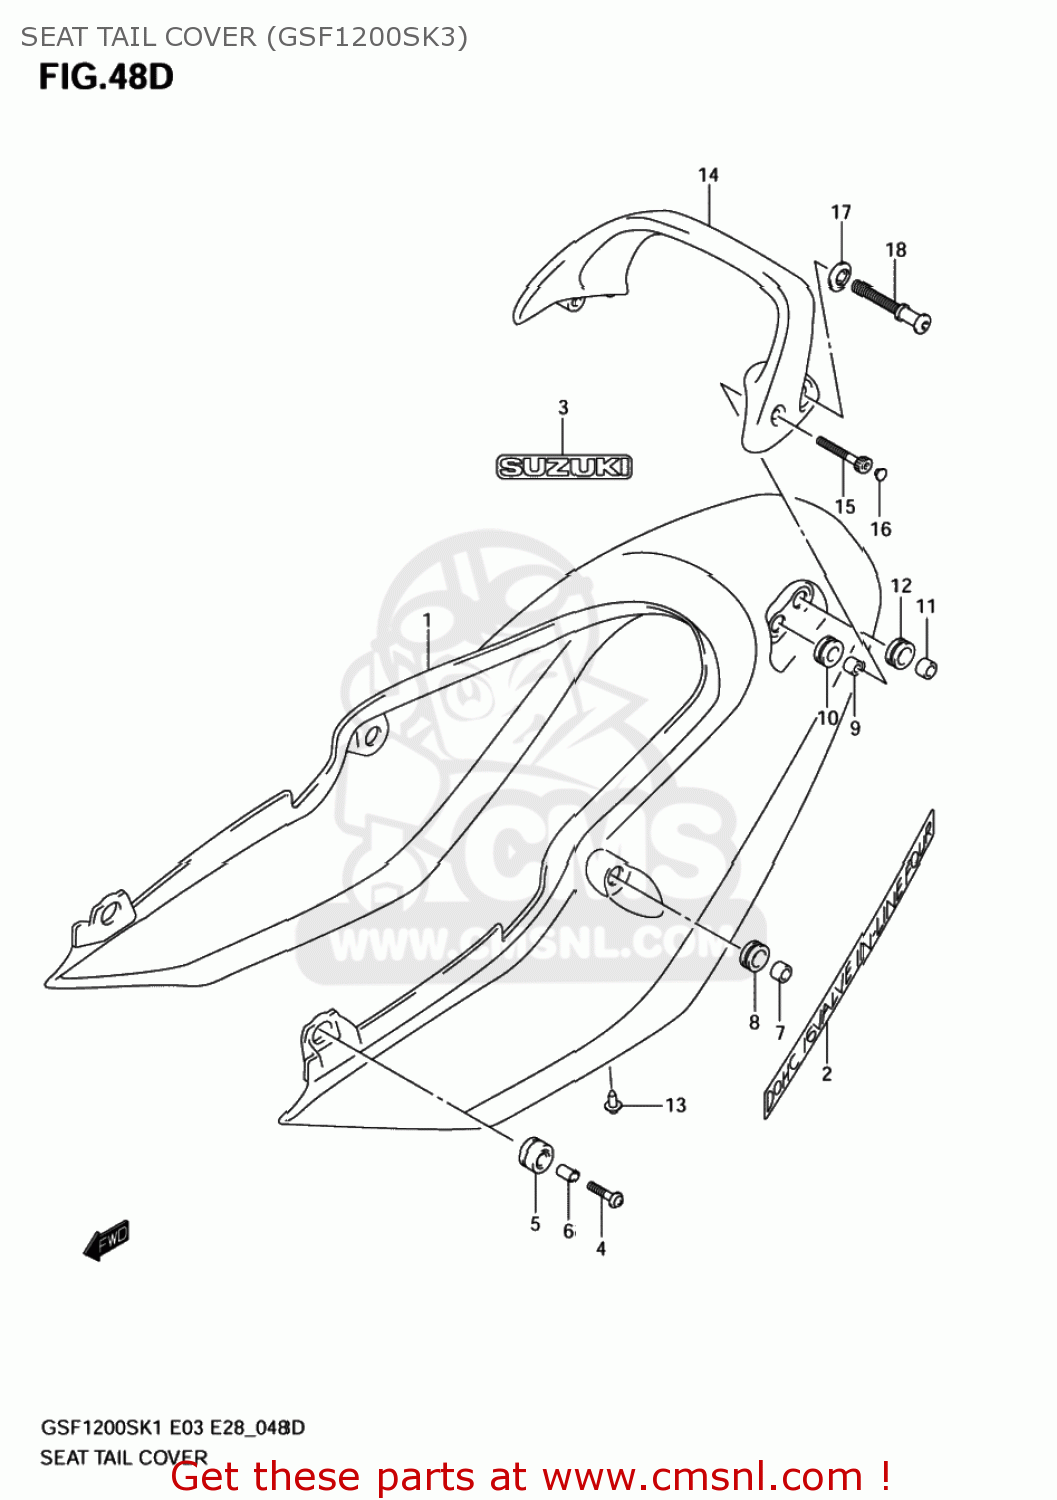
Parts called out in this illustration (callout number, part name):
1	COVER,SEAT TAIL
2	EMBLEM,SEAT TAIL COVER
3	EMBLEM,SUZUKI
4	SCREW(6X30)
5	CUSHION,SEAT TAIL COVER FR
6	SPACER(6.5X10X13)
7	SPACER,8.5X14X9
8	CUSHION
9	SPACER(6.5X12X9)
10	CUSHION
11	SPACER,8.5X14X9
12	CUSHION
13	CLIP(BLACK)
14	HANDLE,PILLION RIDER
16	CAP(OD:10)
17	WASHER,HOOK
18	HOOK,PILLION RIDER HANDLE
